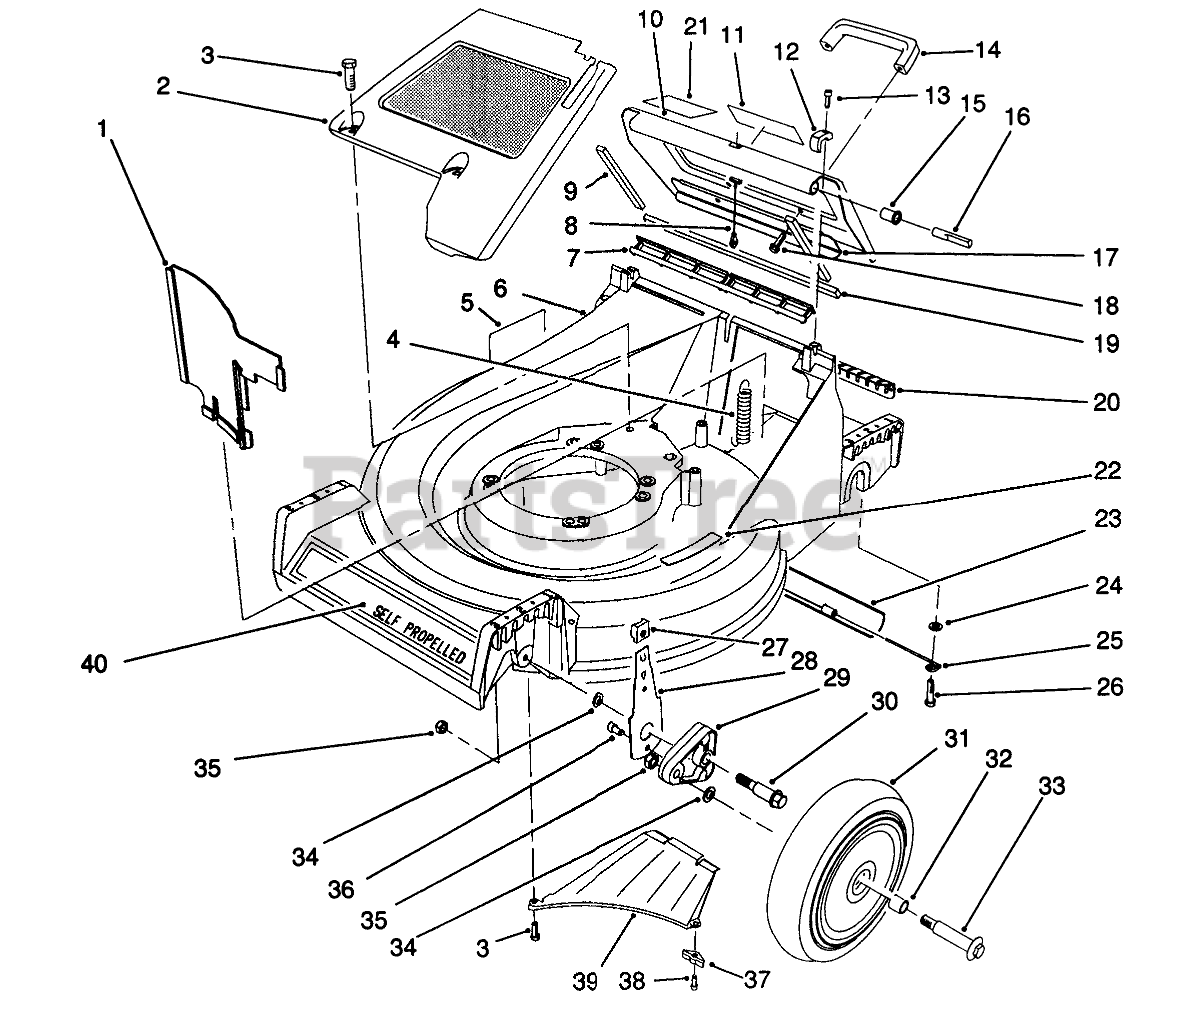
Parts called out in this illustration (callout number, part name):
1	PANEL-VERTICAL
2	PaneI-Screen
3	SCREW-HWHTF
4	EXTENSION-SPRING
5	Decal Danger
6	21" Housing Assembly (Incl. Ref. #5, 22)
7	DOOR SEAL
8	DOOR CABLE
9	DOOR SIDE SEAL
10	Door-Discharge (Incl. Ref. #9, 11, 17 & 19)
11	DECAL - DANGER
12	HINGE CLAMP
13	SCREW-HSH
14	HANDLE-DOOR
15	DOOR BUSHING
16	HINGE PIN
17	DOOR - BRACE
18	SCREW-HWH
19	DOOR END SEAL
20	ACCESS COVER
21	DECAL FRENCH REGUL.
22	DECAL - STEP PAD INT'L
23	TRAILING SHIELD
24	WASHER-PLAIN
25	SHIELD HANGER
26	SCREW-SHOULDER
27	KNOB-ARM
28	FRONT SPRING ARM ASM
29	ARM-PIVOT, FRONT
30	BOLT-SHOULDER
31	Wheel & Tire Assembly (Incl. Ref. #30)
32	BUSHING
33	WHEEL BOLT
34	WASHER
35	NUT-LOCK
36	SCREW-HSH, THREAD FORMING
37	Bracket-Discharge
38	SCREW-HWHTF
39	Ramp Discharge
40	DECAL - 53 CM
